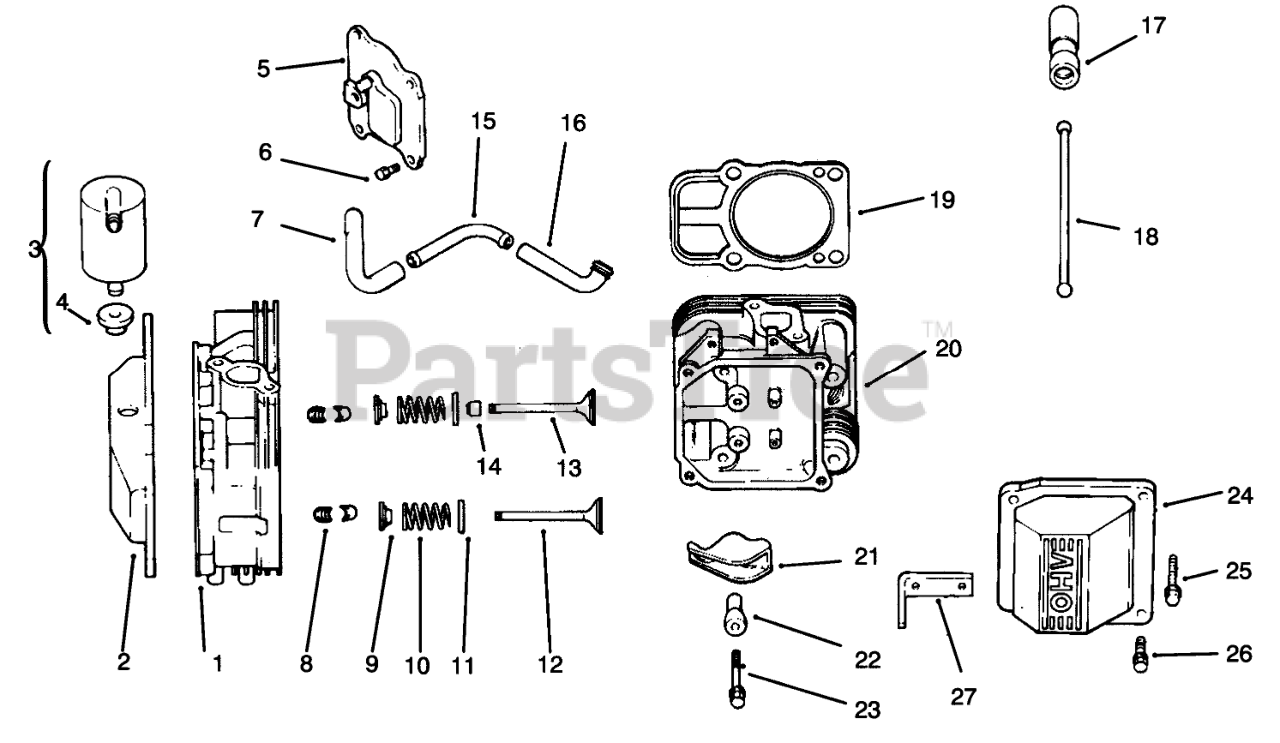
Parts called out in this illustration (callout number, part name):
1	Head ASM-#1 Cylinder (Only On: 72103)
2	Cover-Rocker (Only On: 72103)
3	Kit-Breather INCL 4 (Only On: 72103)
4	Grommet-Rubber (Only On: 72103)
5	Cover-Breather (Only On: 72103)
6	Screw M6x1.0x20 (Only On: 72103)
7	Hose-Breather (Only On: 72103)
8	Kit-Retainer (Only On: 72103)
9	Cap-Valve Spring (Only On: 72103)
10	Spring-Valve (Only On: 72103)
11	Retainer-Spring (Only On: 72103)
12	Valve-Exhaust (Only On: 72103)
13	Valve-Intake (Only On: 72103)
14	Seal-Valve Stem (Only On: 72103)
15	Fitting (Only On: 72103)
16	Hose-Breather (Only On: 72103)
17	Lifter-Valve (Only On: 72103)
18	Rod-Push (Only On: 72103)
19	Gasket-Cylinder Head (Only On: 72103)
20	Head ASM-#2 Cylinder (Only On: 72103)
21	Arm-Rocker (Only On: 72103)
22	Ball-Rocker Pivot (Only On: 72103)
23	Screw M6x1.0x34 (Only On: 72103)
24	Cover-Rocker (Only On: 72103)
25	Screw M10x1.5x91 (Only On: 72103)
26	Screw M6x1.0x30 (Only On: 72103)
27	Strap-Lifting (Only On: 72103)
